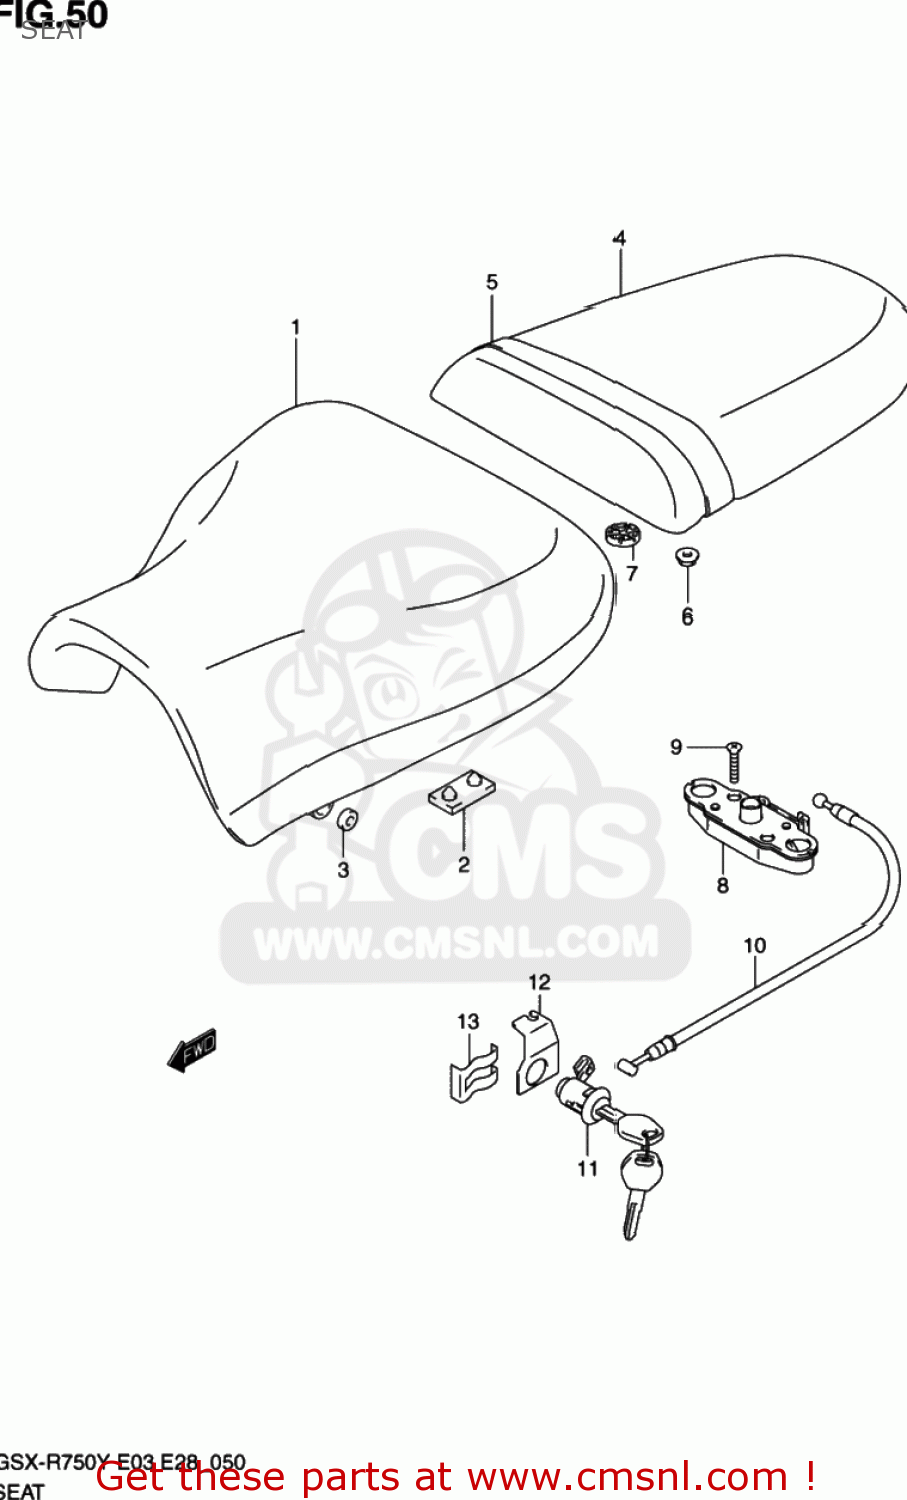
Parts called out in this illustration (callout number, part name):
1	SEAT ASSY
2	CUSHION,SEAT(40X20X6)
3	SPACER,SEAT(6.5X10.5X6)
4	SEAT ASSY,PILLION
5	BAND ASSY,SEAT(BLACK)
6	NUT
7	CUSHION
8	BRACKET,SEAT SUPPORT,RIGHT
9	SCREW
10	CABLE,SEAT LOCK
11	LOCK SET,SEAT
12	GUIDE,SEAT LOCK CABLE
13	PLATE,SEAT LOCK ASSY
